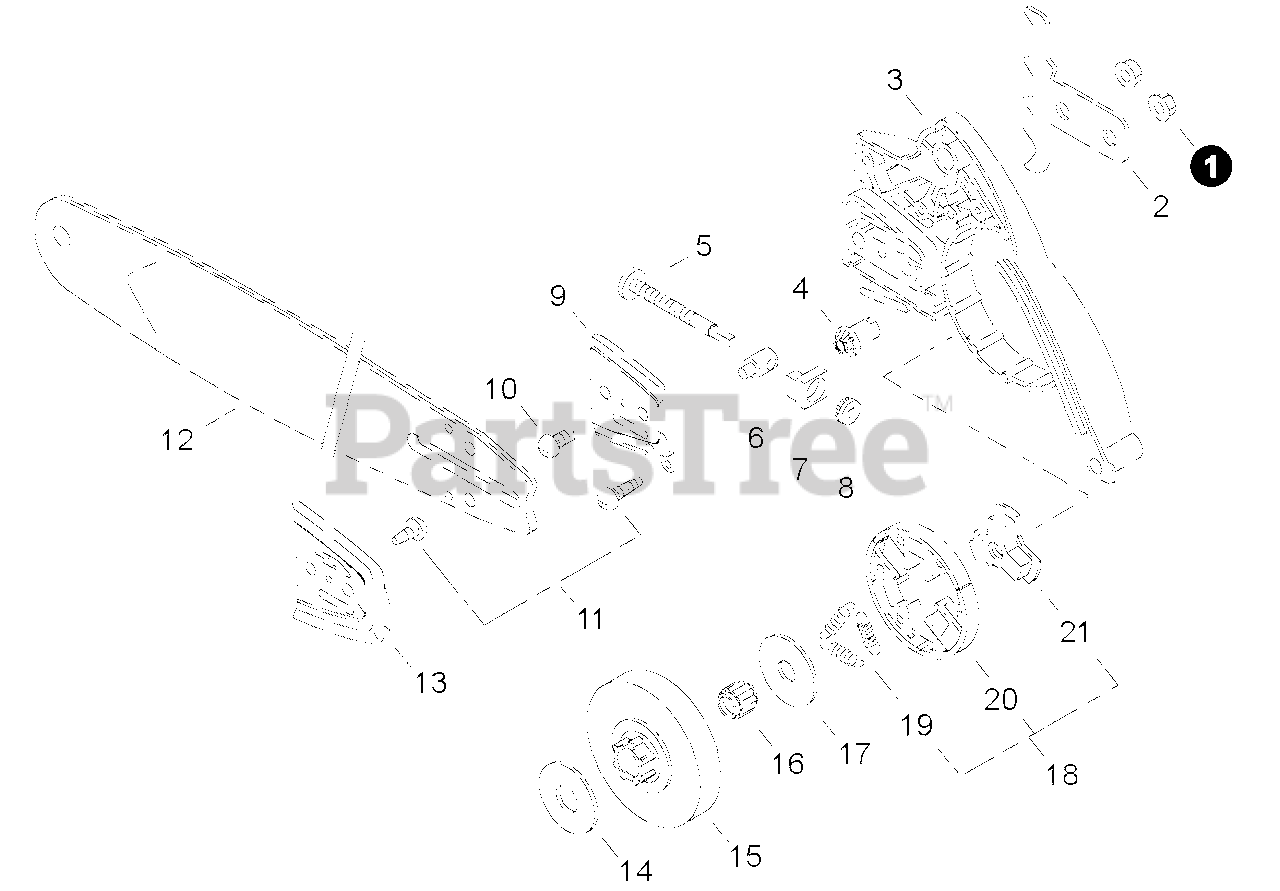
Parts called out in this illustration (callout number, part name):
1	NUT - 8X1.25 -- FLANGE
3	GUARD, SPROCKET
4	GEAR - PINION
5	SCREW, TENSIONER
6	TENSIONER, CHAIN
7	COLLAR - 8
8	GEAR - BEVEL
9	PLATE, GUIDE - OUTER
10	SCREW - 3X5
11	SCREW - 4X10
12	GUIDE BAR - 38" (97cm)
13	PLATE, GUIDE - INNER
14	PLATE, CLUTCH
15	DRUM, CLUTCH
16	BEARING, NEEDLE
17	PLATE, CLUTCH
18	CLUTCH ASSY
19	SPRING, CLUTCH
20	CLUTCH SHOE SET
21	HUB, CLUTCH
